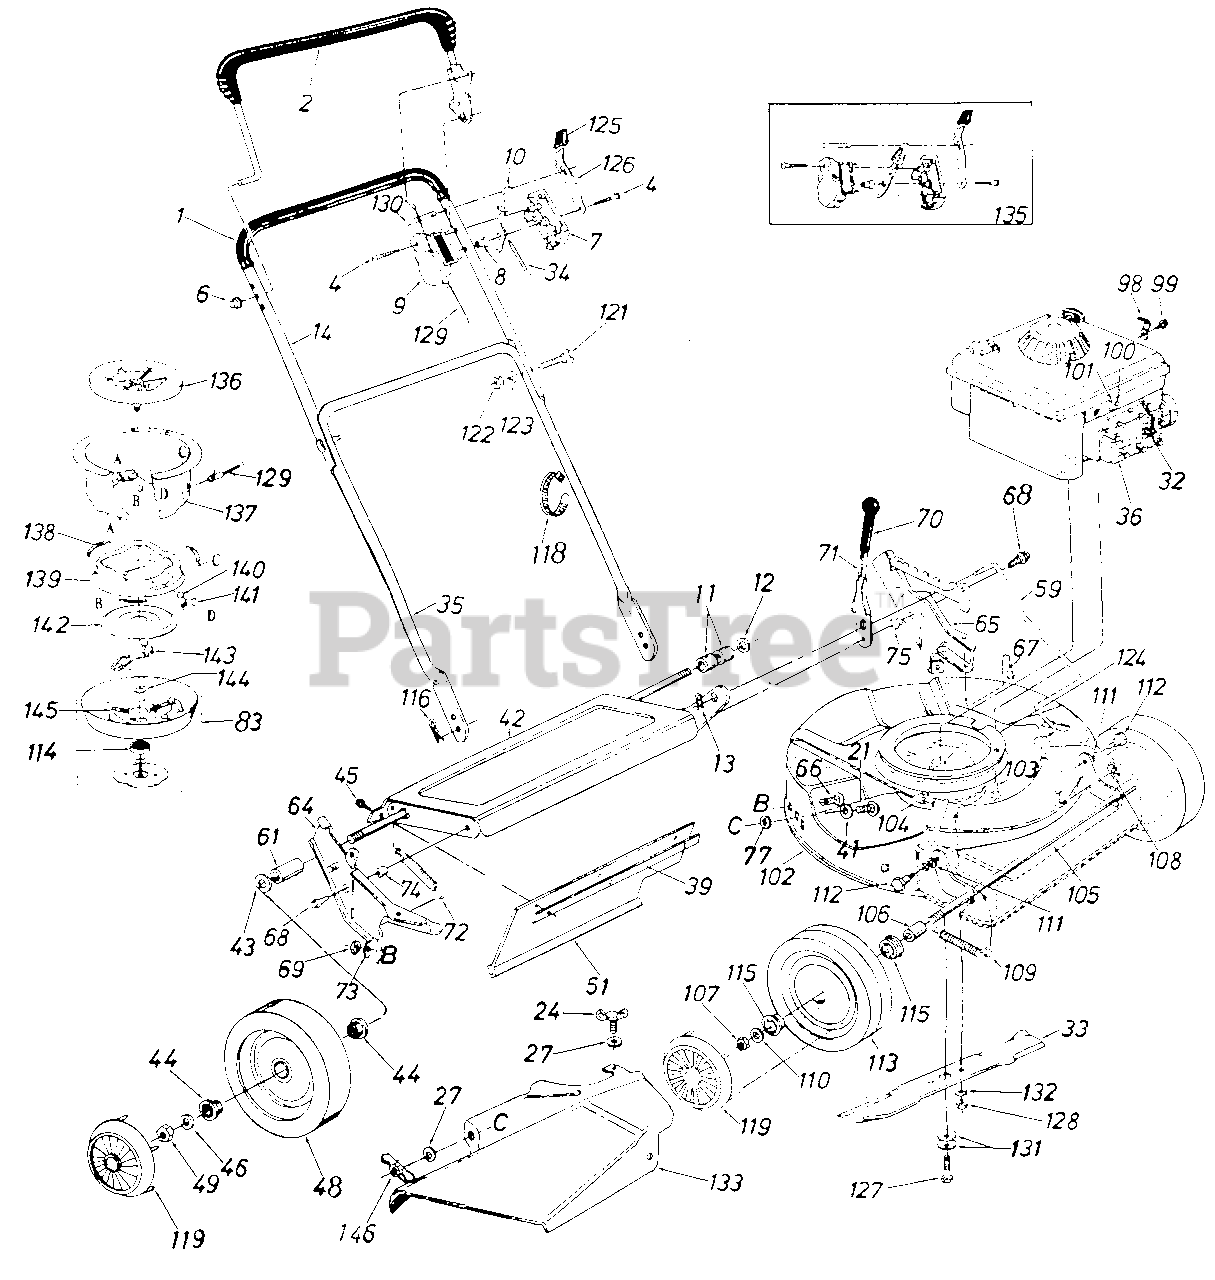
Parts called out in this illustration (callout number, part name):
1	Grip
2	Control Handle Ass'y. L.H.
4	Truss Mach. Scr. #12 x 1.50" Lg.
6	Cap Speed Nut .31 Dia.
7	Control Panel Half
8	Control Disc Pin
9	Clutch Panel Half
10	Throttle Control Lever
11	Spacer .526" I.D. x .690" O.D. x .640" Lg
12	Fl-Wash. .531" I.D. x .930" O.D.
13	Intern. Cotter Pin 5/16" Dia.
14	Upper Handle Chrome
21	Carriage Bolt 1/4-20 x .62" Lg.*
24	Wing Bolt 1/4-20 x .62" Lg.
27	Fl-Wash. .280" I.D. x .620" O.D.
32	Spark Plug Insulator
34	Throttle Control Wire 58.0" Lg.
35	Lower Handle Chrome
36	Engine
39	Retaining Strip
41	Fl-Wash. .344" I.D. x .62" O.D.
42	Rear Axle Ass'y
43	Fl-Wash. .531" I.D. x .930" O.D.
44	Flange Ball Bearing 1/2" I.D.
45	Hex AB-Tap Scr. 1/4 x .62" Lg.
46	Fl-Wash. .531" I.D. x .930" O.D.
48	Rear Wheel Ass'y. Comp 8 x 1.75
49	Hex L-Nut 1/2-20 Thd.
51	Rear Flap 3.75" x 17.30" Lg.
59	Height Adj. Rod 1.50" x 19.42" Lg
61	Spacer .51" I.D. x .69" O.D. x .690" Lg
64	R.H. Handle Wheel Brkt Ass'y
65	L.H. Handle Wheel Brkt Ass'y
66	Carriage Bolt 5/16-18 x .62"*
67	Hex Wash. Hd. B-Tap Scr. 5/1 6-1 8
68	Hex Wash. Hd. TT-Tap Scr. 3/8-1 6
69	Hex Nut 5/16-18 Thd.*
71	Height Adj. Lever 1.25 x 8.5" Lg
72	Extension Spring .50" O.D. x 3.80" Lg
73	Bell-Wash. .345" I.D. x .88" O.D.
74	Spacer.385" I.D. x .502" O.D. x .:270" Lg.
75	Shld. Spacer.500" Dia. x .100
77	Bolt Retainer 1/4 x .50" O.D.
83	Clutch Blade Housing Ass'y.
98	Throttle Control Cable Clip
99	Hex B-Tap Scr. #10 x .38" Lg .
100	Hex Sems Bolt #10-32 x .62" Lg.
101	Casing Clamp
104	Speed Nut 1/4-20 U-Type
105	Front Axle Ass'y.
106	Sleeve .526" I.D. x .690" O.D. x .880" Lg.
107	Hex L-Nut 1/2-20 Thd.
108	Intern. Cotter Pin 5/16" Dia.
109	Extension Spring .50" O.D. x 3.20" Lg
110	Fl-Wash. .531" I.D. x .930" O.D.
111	Intern. L-Wash. 3/8 x .56" O.D.
112	Shld. Bolt .623" Dia. x .425
113	Front Wheel Ass'y. Comp 7 x 1.75
114	Ball Brg. .669" I.D. x 1.574"
115	Flange Ball Bearing 1/2" I.D.
116	Intern. Cotter Pin 5/16" Dia.
118	Cable Tie Triple Loop .875 Dia.
119	Hub Cap Plastic
121	Curved Carr. Bolt 5/16-18 x 1.38 " Lg .
122	Hex Nut 5/16-18 Thd.*
123	L-Wash. 5/16" I.D.*
124	Blade Brake Clutch Comp.
125	Spring Lever Knob
126	Lockout Spring
127	Hex Cent. L-Bolt 3/8-24 x 2.00" (Grade 8)
128	Hex Nut 3/8-24 Thd. (Grade 8)
129	BBC Clutch Cable x 46.0" Lg.
130	Lock Pin .314" Dia. x 1.75" Lg.
131	Bell-Wash. .400" I.D. x .88" O.D.
132	L-Wash. 3/8" I.D.*
133	Side Chute Deflector
135	Kit Control Housing Comp.
137	Clutch Housing
138	Extension Spring .35" O.D. x 1.75" Lg.
139	Brake Cup Cone
140	Steel Ball .500" Dia.
142	Clutching Cone
143	Hex Tap L-Scr. 1/4-20 x .75" Lg .
144	Fl-Wash. .690" I.D. x 1.060" O.D.
145	Compression Spring .35" O.D. x 2.00" Lg.
